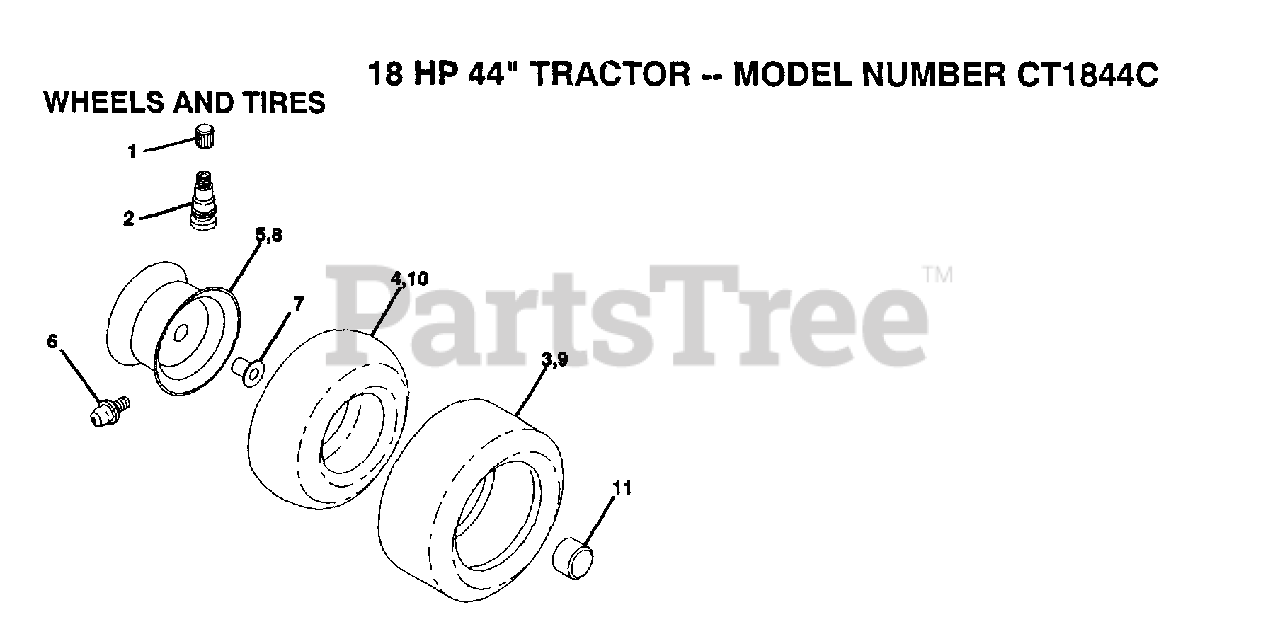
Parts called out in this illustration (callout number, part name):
1	VALVE CAP
2	VALVE STEM LT
4	TUBE.5.3/4.5/6
6	FITTING LT
7	"FLANGE, BEARING"
9	TIRE REAR T
10	TUBE.18X9.5-8
11	HUB CAP
